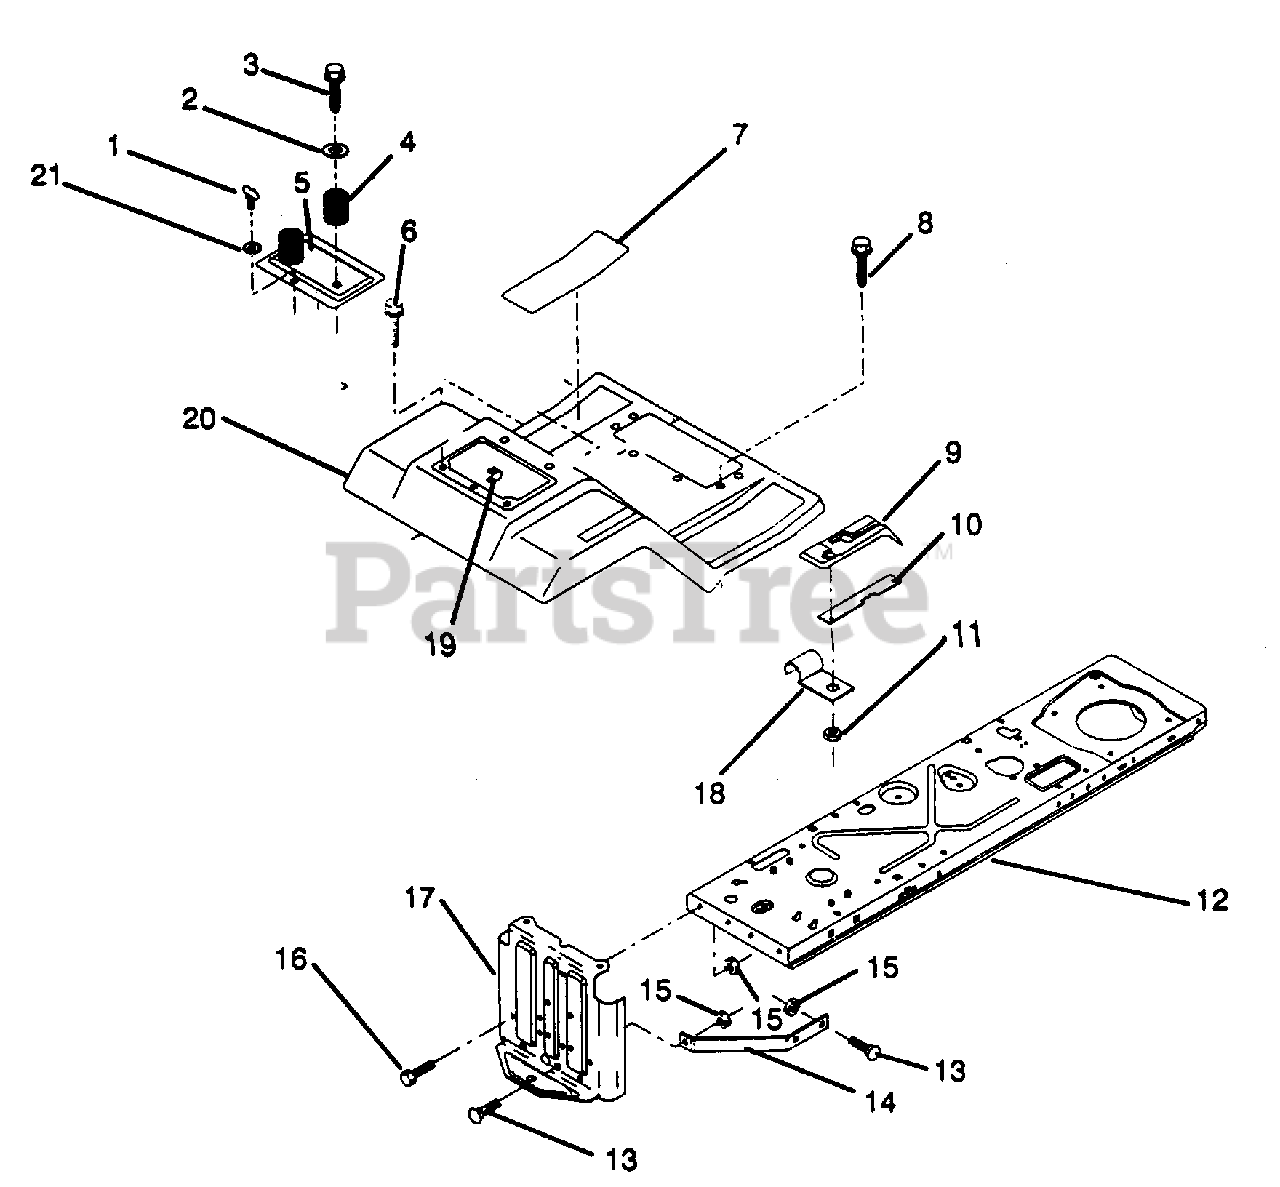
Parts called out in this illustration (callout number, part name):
1	Stud 1/4 Turn
2	Washer 13/32 x 1-1/4 x 12 Ga. (AYP part number)
3	Screw, Hex Wsh. Thrdrol. 3/8-16 x 3/4 (AYP part number)
4	Spring, Compression, Seat (AYP part number)
5	Door, Fender (AYP part number)
6	Screw, Hex Wsh. Thrdrol. 5/16-18 x 1/2 (AYP part number)
7	Pad, Footrest (AYP part number)
8	Screw, Hex Wsh. Thrdrol. 5/16-18 x 3/4
9	Console, Shift Control (AYP part number)
10	Bar, Shift Lock (AYP part number)
11	Palnut (AYP part number)
12	Assembly, Frame (AYP part number)
13	Bolt, Carriage 5/16-18 UNC x 3/4
14	Brace, Drawbar (AYP part number)
15	Nut, Crownlock 5/16-18
16	Bolt, Hex Hd. 5/16-18 UNC x 3/4 (AYP part number)
17	Drawbar (AYP part number)
18	Clip, Insulated (AYP part number)
19	Receptacle 1/4 Turn (AYP part number)
20	Fender/Footrest (AYP part number)
21	Retainer 1/4 Turn (AYP part number)
